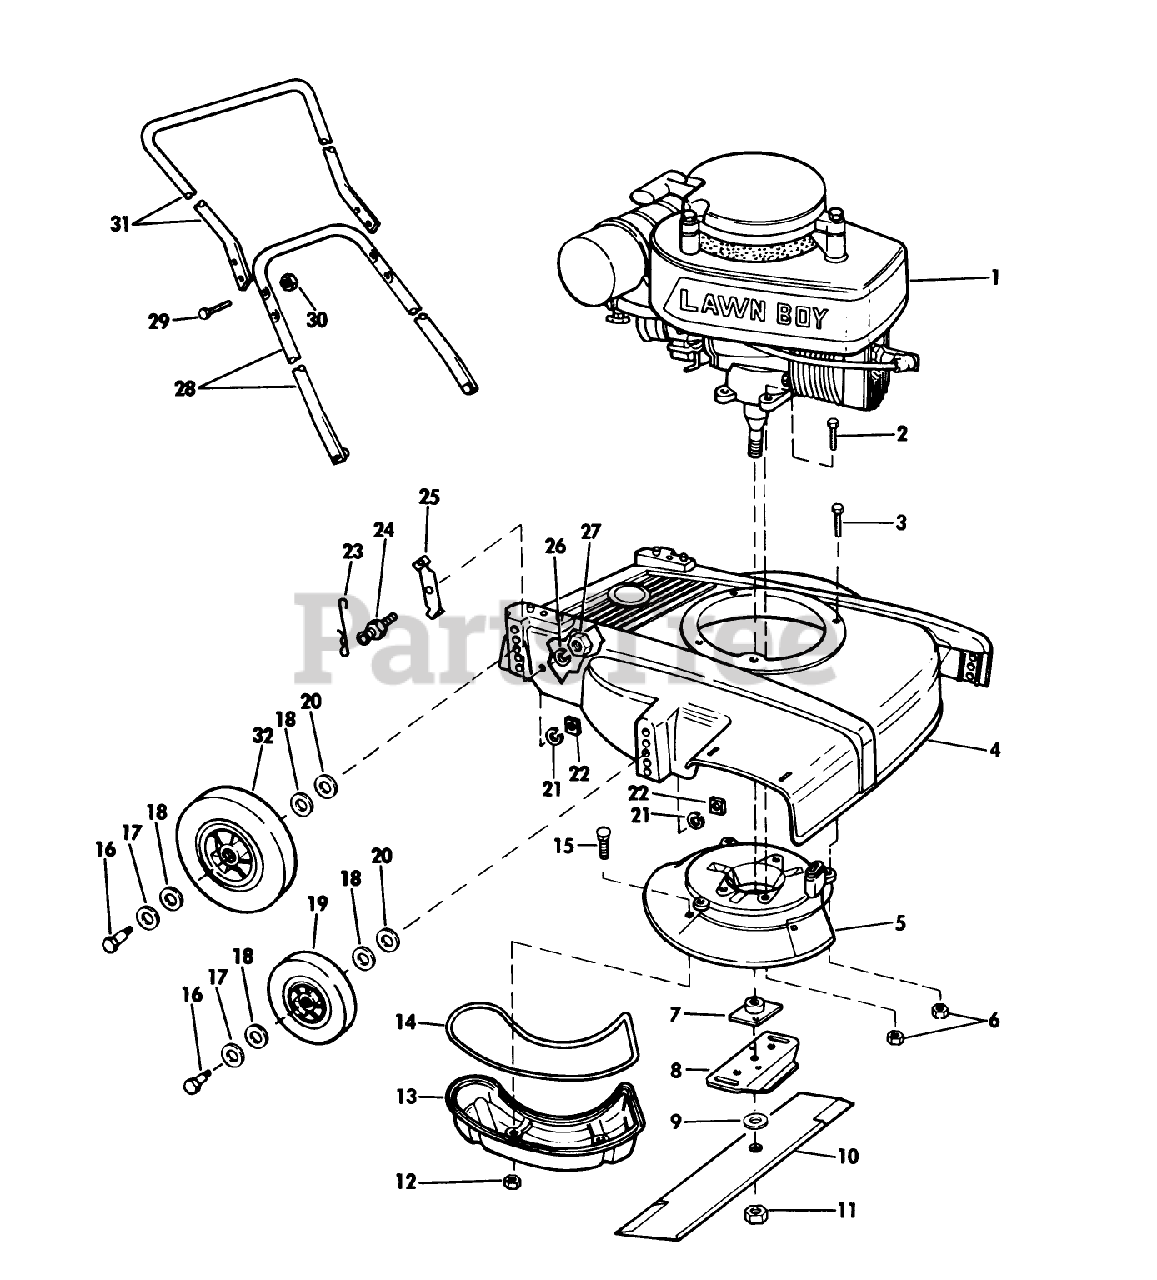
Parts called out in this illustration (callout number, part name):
7	PLATE AND COLLAR ASM
11	NUT-BLADE
12	LOCKNUT E
20	WASHER WROUGHT
21	WASHER, LOCK
26	Lockwasher
